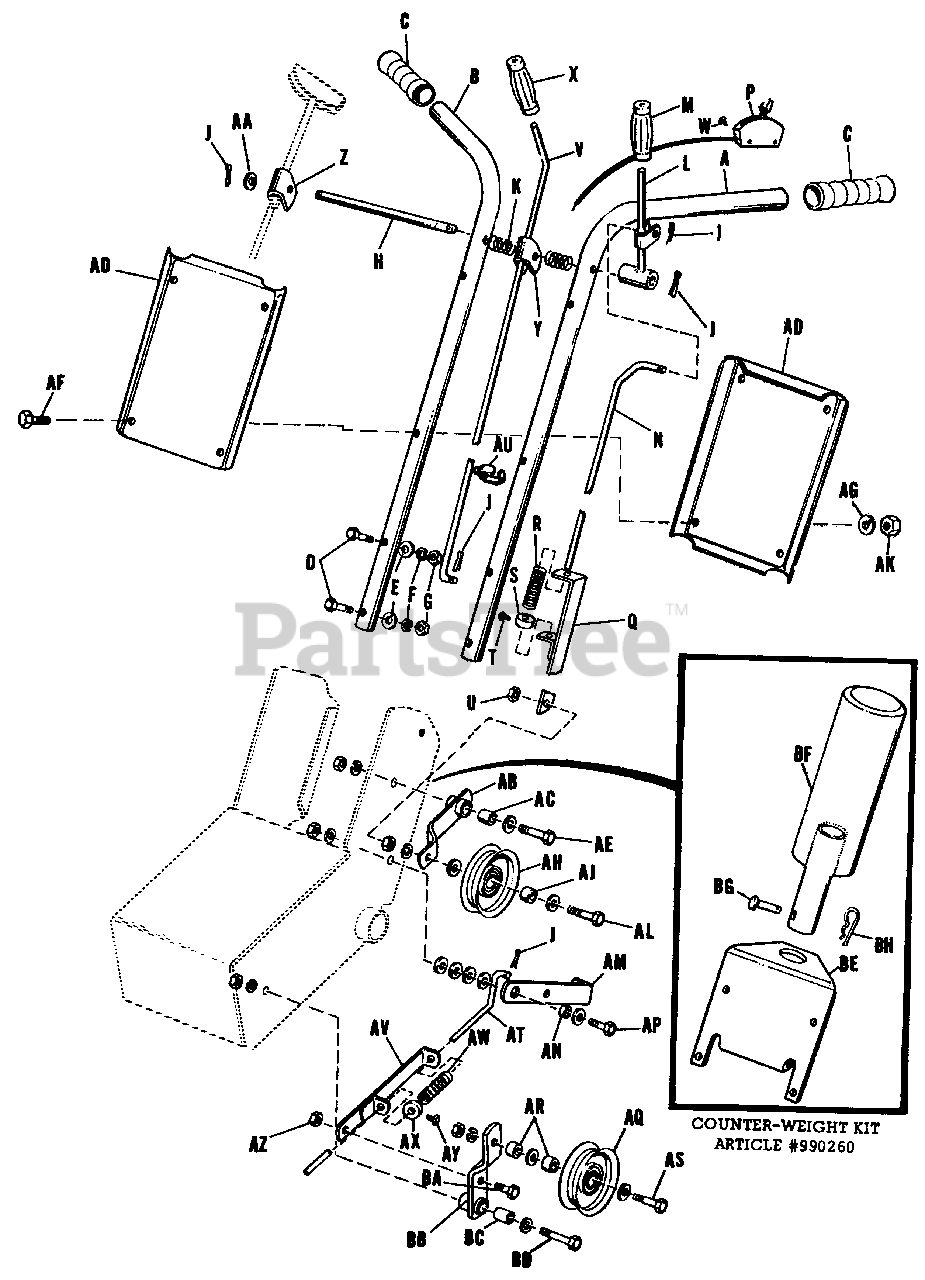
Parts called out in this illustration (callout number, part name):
A	Handle, Left Hand
B	Handle, Right Hand
C	Grip, Handle
D	Capscrew, Hex, 3/8"-16 NC x 2" lg.
E	Washer, Plain, 3/8"
F	Washer, Lock, 3/8"
G	Hex Nut Full 3/8"-16 NC
H	Pin, Lever
J	Pin, Cotter, 3/32" x 3/4" lg.
L	Lever Assembly, Left Hand
N	Rod, Clutch Transmission
P	Throttle Control Assembly
Q	Guide Assembly, Rod (20" long)
T	Set Screw, Square Hd. 1/4"-20 NC x 3/8" lg.
U	Hex Nut Full Lock, 3/8"-16 NC
V	Rod, Reverse
W	Self Tapping Screw, Rd. Hd., #10-24 x 1" lg.
Y	Guide, Reverse Rod
Z	Guide, Rod
AA	Washer, Plain, 5/16"
AB	Lever Assembly, Idler, Transmission Clutch
AC	Race, Inner Bearing
AE	Capscrew, Hex, 3/8"-16 NC x 1-3/4" lg.
AH	Pulley, Idler (Transmission Drive)
AL	Capscrew, Hex, 3/8"-16 NC x 1-3/4" lg.
AM	Pedal, Clutch, Foot
AP	Capscrew, Hex, 3/8"-16 NC x 1-1/2" lg.
AQ	Pulley, Idler (Rotor Drive)
AS	Capscrew, Hex, 3/8"-16 NC x 1-3/4" lg.
AT	Rod, Clutch Rotor
AU	Cable Clip
AV	Guide Assembly, Clutch Rod
AX	Collar, Set
AY	Set Screw, Square Hd., 1-1/4"-20 NC x 3/8" lg.
AZ	Hex Nut, Full, Lock, 3/8"-16 NC
BA	Capscrew, Hex, 3/8"-16 NC x 3/4" lg.
BB	Lever Assembly, Idler
BC	Race, Inner Bearing
BD	Capscrew, Hex, 3/8"-16 NC x 1-3/4" lg.
